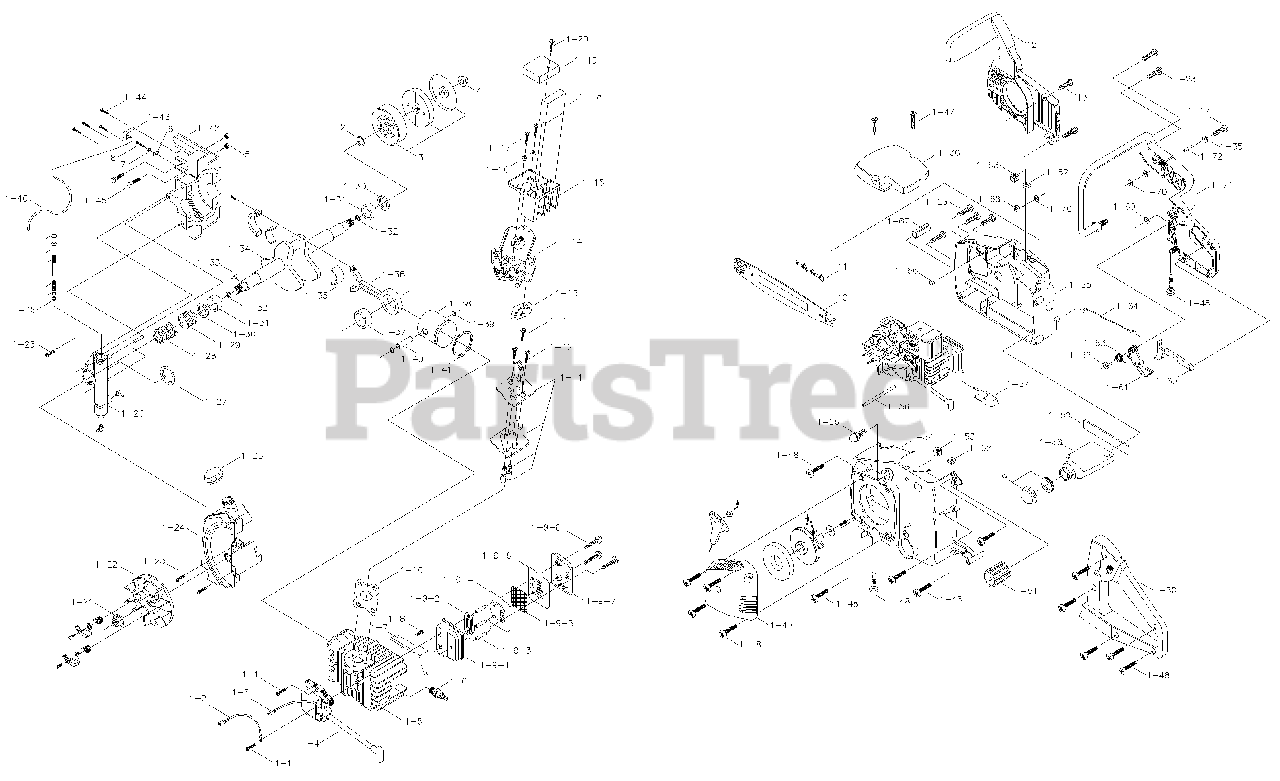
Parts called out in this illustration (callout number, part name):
1	POWERHEAD ASS'Y
1-2	WIRE ASS'Y, GROUND
1-3	WIRE ASS'Y, STOP SWITCH
1-4	IGNITION ASS'Y
1-7	BAFFLE, AIR
1-9	MUFFLER ASS'Y
1-9-1	COVER, MUFFLER
1-9-2	PLATE, REINFORCING
1-9-3	SPACER, MUFFLER
1-9-4	BAFFLE, OUTER
1-9-5	BAFFLE, INNER MUFFLER
1-9-6	SCREEN, SPARK ARRESTER
1-9-7	COVER, MUFFLER
1-10	GASKET, INSULATOR
1-11	INSULATOR ASS'Y
1-14	CARBURETOR
1-15	BOX,AIR FILTER
1-17	SCREW
1-18	FILTER, AIR
1-19	SHIELD,CARBURETOR
1-22	FLYWHEEL ASS'Y
1-24	FUEL TANK ASS'Y
1-25	CAP, FUEL ASS'Y
1-26	OIL PUMP ASS'Y
1-29	WORM GEAR
1-30	SEAL, C'SHAFT OIL
1-34	CRANKSHAFT
1-36	COVER, AIR FILTER
1-38	PISTON
1-41	PISTON RING
1-44	SCREW
1-45	BOLT, BAR
1-49	STARTER HOUSING ASS'Y
1-50	HANDLE ASS'Y, LEFT
1-51	ISOLATOR,RUBBER
1-53	RETAINER,NUT
1-54	ENGINE HOUSING, LEFT
1-57	SLIDE, CHOKE
1-58	OIL TANK ASS'Y
1-59	SPACER, OIL TANK
1-60	LATCH, THROTTLE
1-61	TRIGGER,THROTTLE
1-64	CABLE,THROTTLE
1-65	ENGINE HOUSING, RIGHT
1-66	FILTER, FOAM
1-68	NUT
1-71	HANDLE ASS'Y, RIGHT
3	DRUM ASS'Y
7	RING, RETAINING
9	OIL CAP ASS'Y
12	CHAIN BRAKE ASS'Y
